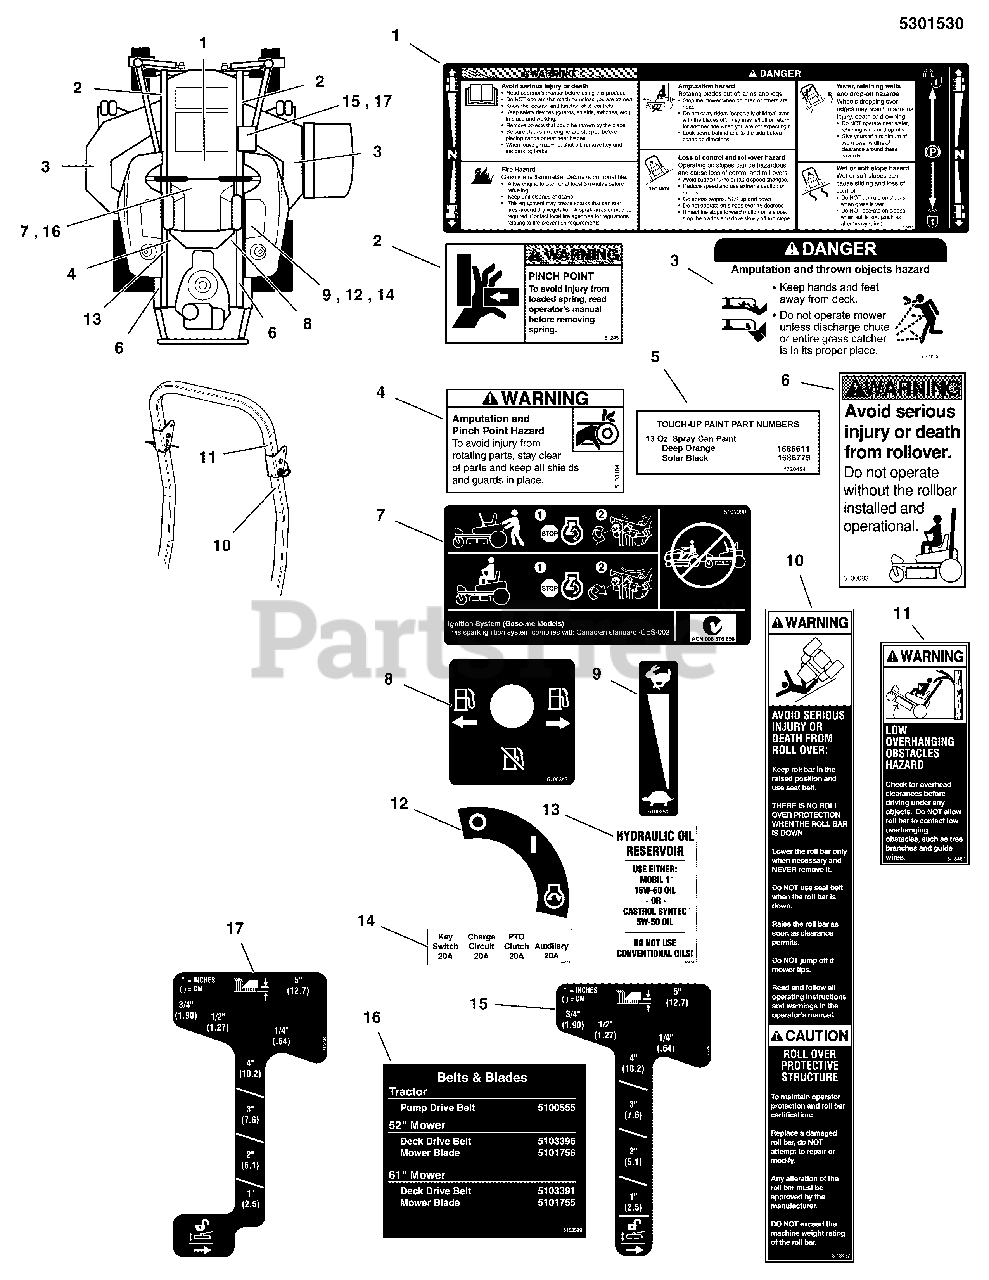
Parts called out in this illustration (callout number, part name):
1	DECAL, MAIN SAFETY
2	DECAL, PINCH POINT
3	DECAL, DANGER DO NOT OPERATE W/O DEFLECT
4	DECAL, WARNING, HAND IN BELT, ENG ONLY
5	DECAL-TOUCH UP PAINT ORANGE,BLACK,RED
6	DECAL, WARNING, ROLL BAR
7	DECAL, CZT HYRDO RELEASE
8	DECAL, FUEL VALVE
9	DECAL, THROTTLE CONTROL
11	DECAL, WARNING OVERHANG, ROPS (SV)
12	DECAL, IGNITION SWITCH
13	DECAL, OIL RESEVOIR
14	DECAL, FUSE LOCATION
15	DECAL-HEIGHT CITATION
16	DECAL, BELT & BLADE, COBALT & IS1500ZX
17	DECAL, CUT HEIGHT
